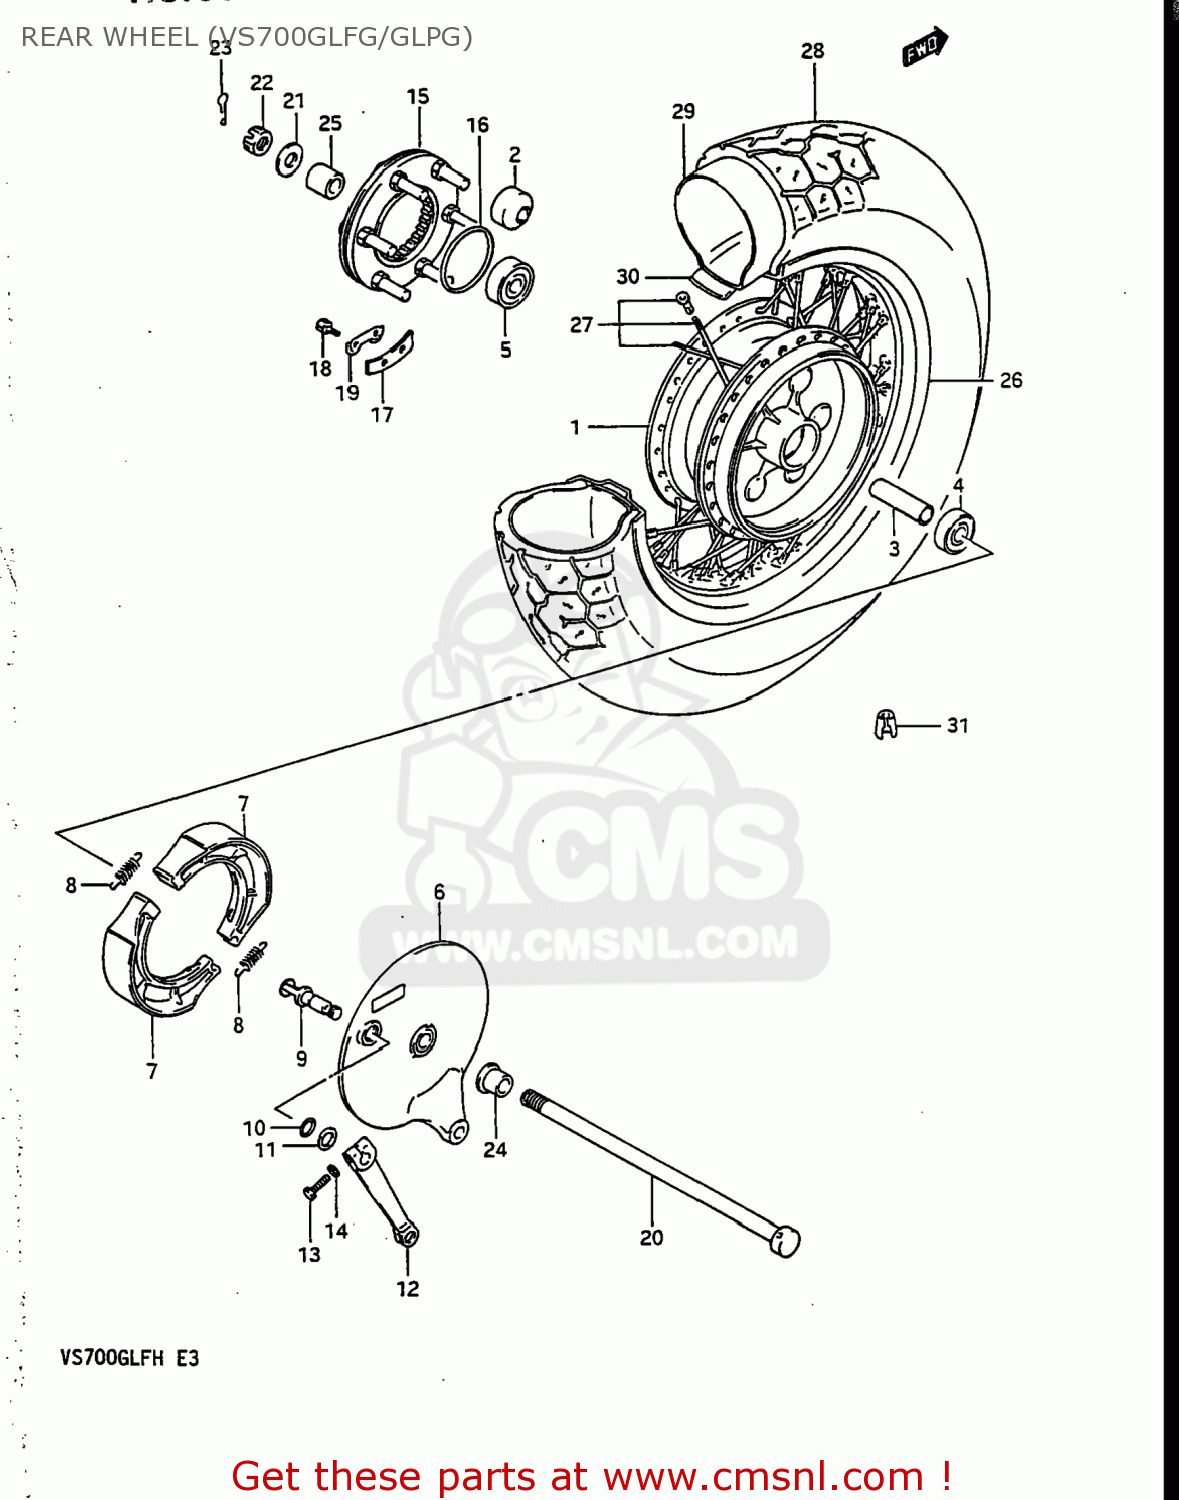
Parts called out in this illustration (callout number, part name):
1	HUB SET,REAR
2	BUSHING
3	SPACER,REAR HUB BEARING
4	BEARING
5	BEARING
6	PANEL,REAR BRAKE ANCHOR
7	SHOE SET,BRAKE (MCA)
8	SPRING,BRAKE SHOE
9	CAM,RR BRAKE
10	O-RING,BOSS
11	WASHER (15X24X1.6)
12	LEVER,RR BRAKE CAM
13	BOLT
14	WASHER,LOCK
15	JOINT ASSEMBLY,REAR HUB DRUM
16	O RING(D:2.1,ID:65)
17	WASHER,THRUST(T:1.6)
18	BOLT(6X16)
19	WASHER
20	AXLE,REAR
21	WASHER(16.5X36X3.2)
22	NUT
23	COTTER PIN
24	SPACER,REAR AXLE,RIGHT
25	SPACER,REAR AXLE,LEFT
26	RIM,REAR WHEEL
27	SPOKE SET,REAR WHEEL
28	TIRE
29	TUBE ASSEMBLY,WHEEL,INNER
30	PROTECTOR,WHL INR TUBE
31	BALANCER,WHEEL
